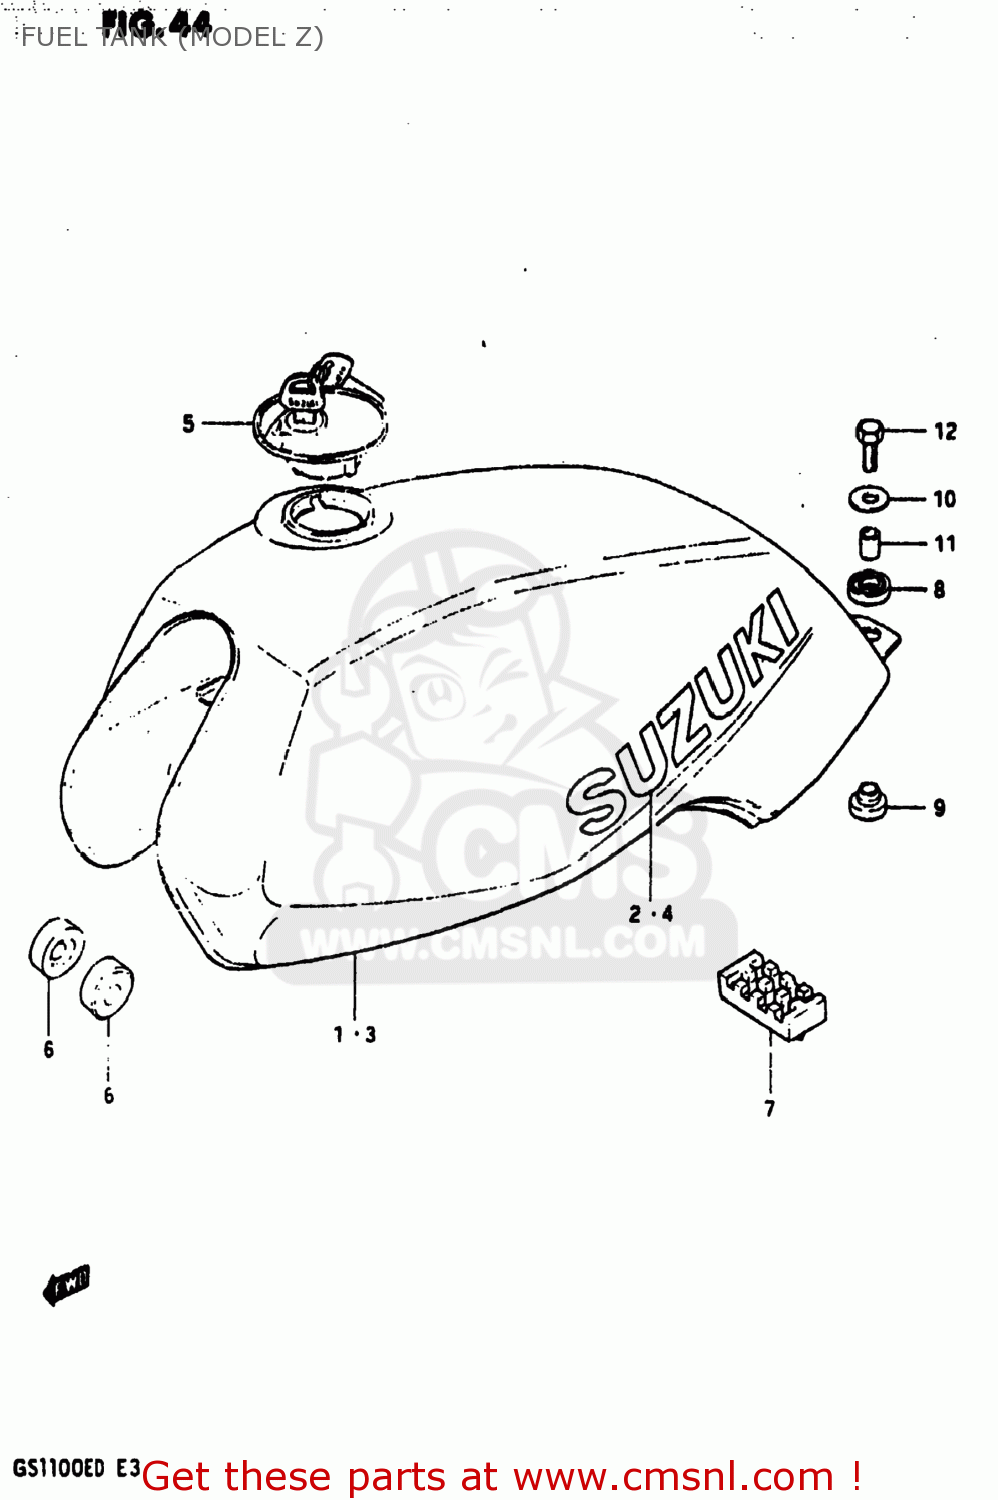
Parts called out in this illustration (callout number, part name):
1	TANK ASSEMBLY,FUEL
2	EMBLEM
3	TANK ASSEMBLY,FUEL
4	EMBLEM
5	CAP SET,FUEL TANK
6	CUSHION
7	CUSHION,FUEL TANK CTR
8	CUSHION
9	CUSHION
10	WASHER (6.5X24X1.6)
11	SPACER
12	BOLT
